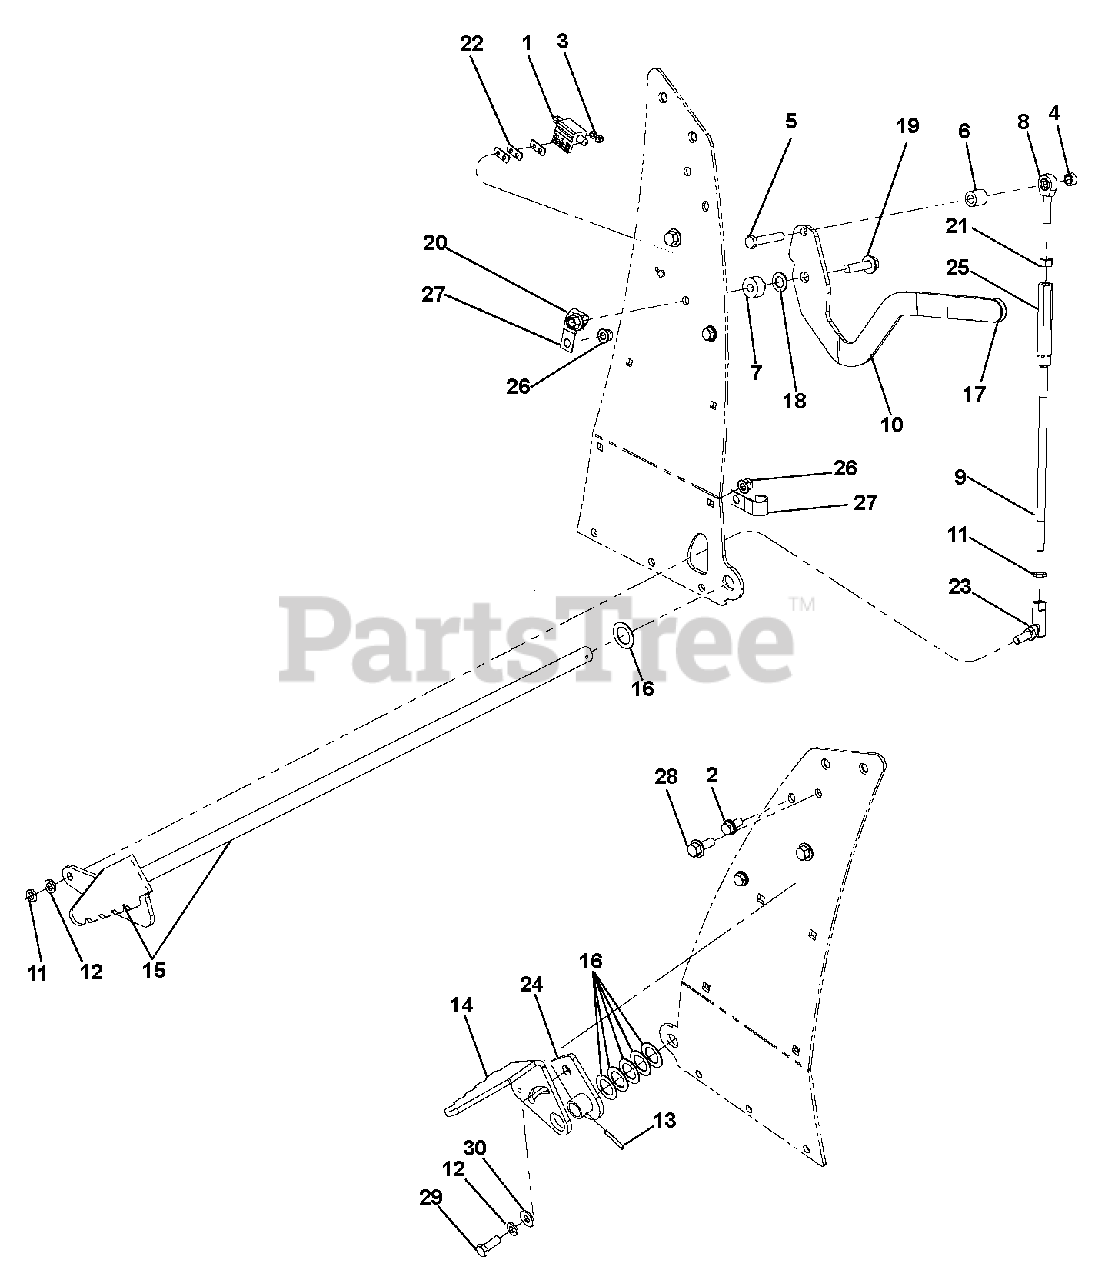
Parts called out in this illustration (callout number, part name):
1	Switch
2	Screw, Cap Special
3	Nut, Nyloc M5 x .8
4	Nut, Lock, Crown 3/8-16 GR5
5	Bolt, Hex .38-16 x 2.00 GR5
6	Bushing .431 x .750 x .787
7	Bushing Assembly
8	End, LH Tie Rod
9	Rod, Threaded .38-24
10	Lever, Brake Handle
11	Nut, .38 UNF Hex Grade 5
12	Locking Washer .38 x .094 Regular
13	Pin, Spring
14	Arm, Right Hand Brake
15	Weldment, Brake Shaft
16	Washer, Steel JDS24 .891 x 1.375 x .048
17	Grip
18	Washer, Steel JDS24 .531 x .938 x .060
19	Screw, Hex, Flat, M10 x 1.5 x 40 10.9
20	Locknut, Flat M10 x 1.5-10
21	Nut, Jam .375-24 LH
22	Strip, Back-Up
23	Ball Joint, 3/8 x 24
24	Weldment, Torque Arm
25	Turnbuckle
26	Locknut, M8 x 1.25 Nyloc Flange 10Y
27	P-Clip, .500 Insulated
28	Screw, Hex, Flat M10 x 1.5 x 25
29	Bolt, Hex .38-16 x 1.00
30	Washer, Flat Steel, .38 x .875 x .083
